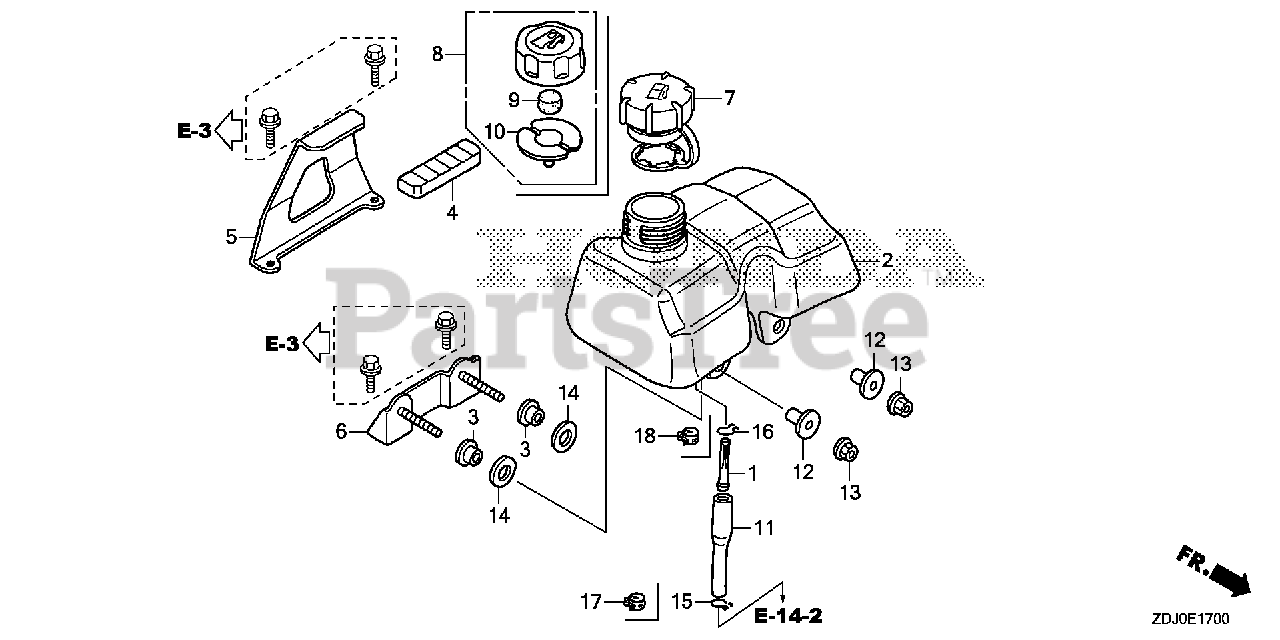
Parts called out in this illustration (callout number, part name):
1	FILTER, FUEL
2	TANK, FUEL
3	RUBBER A, TANK MOUNTING
4	RUBBER B, TANK MOUNTING
5	STAY A, FUEL TANK
6	STAY B, FUEL TANK
7	CAP ASSY., FUEL TANK
11	TUBE, FUEL
12	COLLAR, CANISTER MOUNTING
13	NUT, SELF-LOCK (6MM)
14	WASHER, PLAIN (15MM)
17	CLIP, TUBE (D8)
18	CLIP, TUBE (10.5MM)
